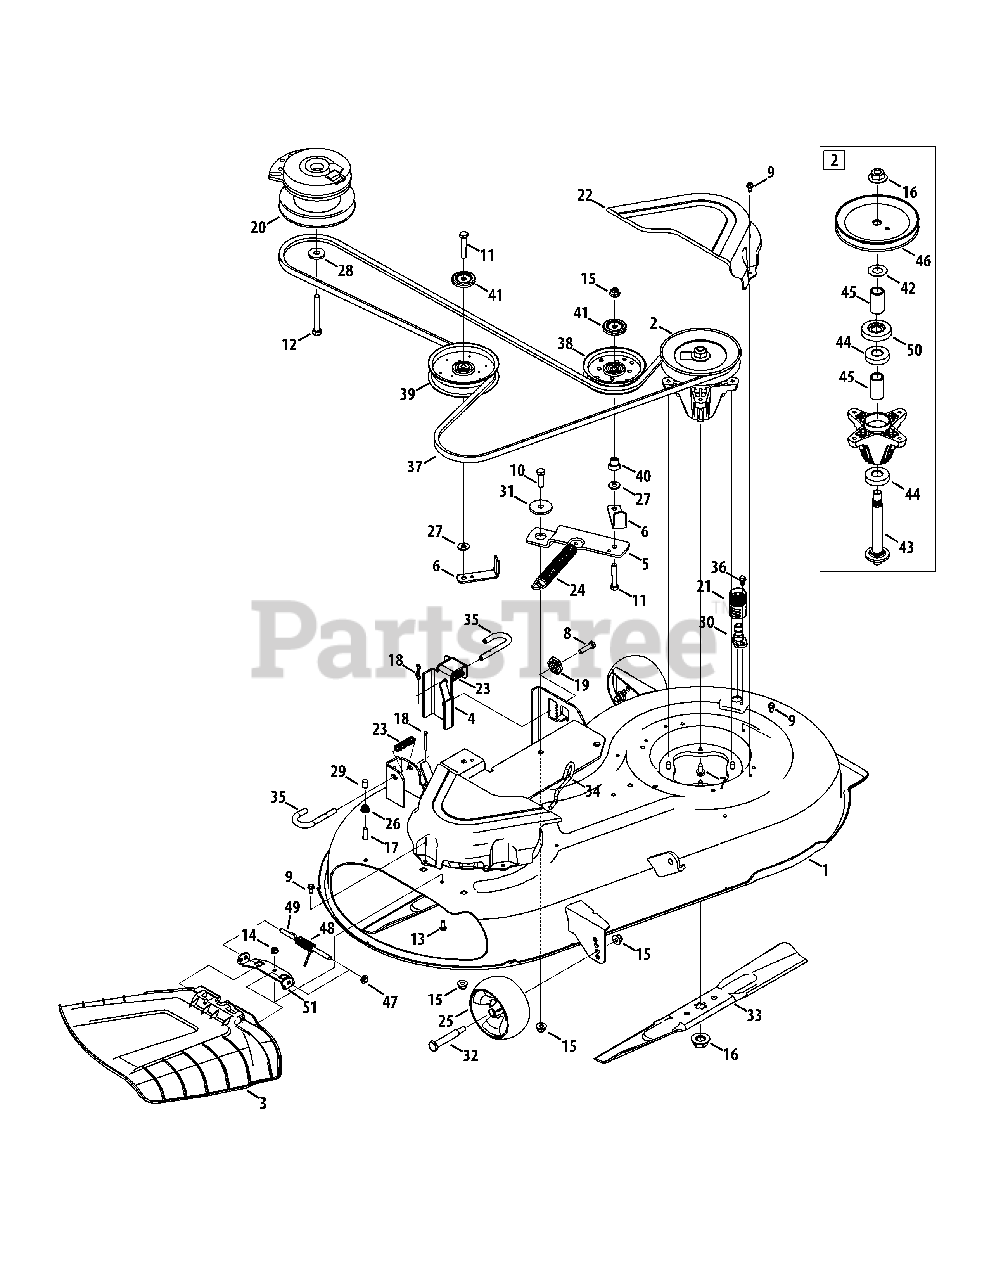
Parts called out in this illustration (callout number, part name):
1	42" Deck
2	Spindle Assembly
3	Chute Deflector Assembly
4	Deck Lift Bracket
5	Pivot Idler Bracket
6	Bracket Belt Guard
7	Hex Washer Screw, 5/16-18 x .750
8	Hex Cap Screw, 3/8-16 x 1.50
9	Hex Washer Screw, 1/4-20 x .625
10	Hex Cap Screw, 3/8-16 x 1.25
11	Hex Cap Screw, 3/8-16 x 2.00
12	Screw, 7/16-20 x 3.25
13	Hex Cap Screw, 1/4-20 x .62
14	Nut, Flange Lock, 1/4-20, Nylon
15	Flange Lock Nut, 3/8-16
16	Hex Flange Nut, 5/8-18
17	Hex Cap Screw, 5/16-18 x 1.00
18	Cotter Pin, 5/32 x 1.25
19	Deck Adjustment Gear
20	Electric PTO Clutch
21	Water Nozzle Adapter
22	Belt Cover
23	Compression Spring, .66 x 1.9
24	Extension Spring, .94 Dia. x 7.57
25	Deck Ball Wheel, 5.0
26	Flange Lock Nut, 5/16-18
27	Flat Washer, .385 x .870 x .092
28	Flat Washer, .450 x 1.25 x .164
29	Cap, .290 x .500
30	Deck Wash Nozzle
31	Shoulder Spacer, .884 x .190
32	Shoulder Screw, .5 x 2.5 x 3/8-16
33	Blade, 2 in 1, 21.23
34	Deck Spring Rod
35	Deck Hanger Rod
36	Shoulder Screw, 1/4-20 x 0.50
38	Idler Pulley, 4.25 Dia.
39	Idler Pulley, 5.00 Dia.
40	Shoulder Spacer
41	Pulley Cap
42	Washer, .760 x 1.50 x .030
43	Spindle Shaft
44	Ball Bearing
45	Spacer, .792 x 1.060 x 1.860
46	Deck Pulley
47	Push Cap
48	Spring, Torsion, .440 ID x 1.75
50	Bearing Shield
